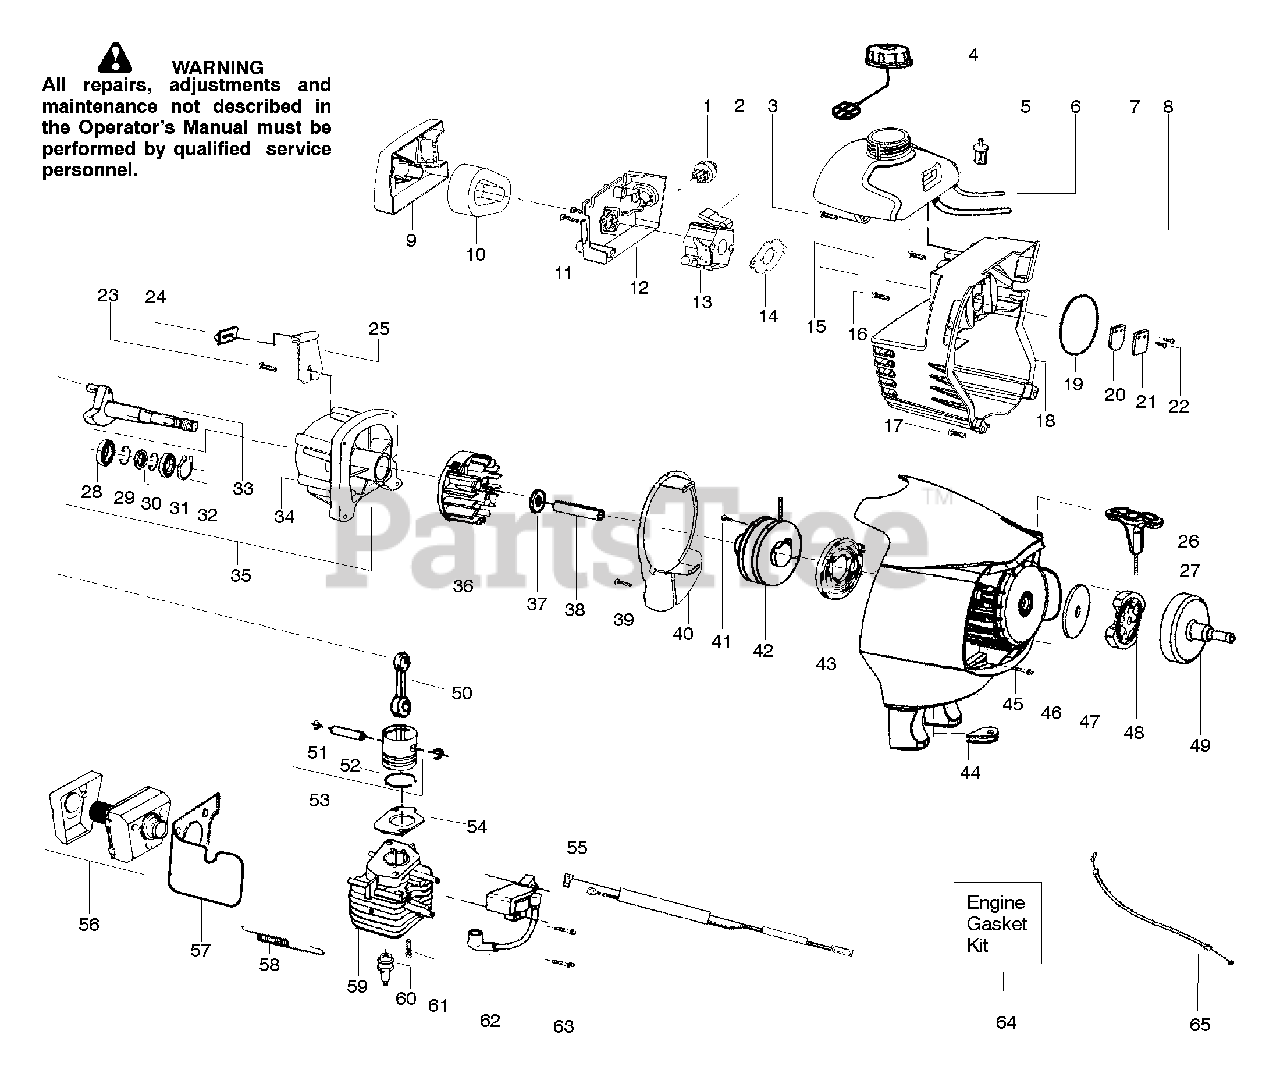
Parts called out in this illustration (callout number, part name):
1	Bulb-Purge
2	Kit-Choke Lever
3	Screw-tank
4	Cap-Fuel w/ret.
5	Assy-Fuel pickup
6	Kit-Fuel line
7	Kit-Fuel/Purge line
9	Cover-Air box
10	Filter-Air
11	Screw-Carb.
13	Assy-Carb (WT628)
14	Gasket-Carb. (kit)
15	Assy-Fuel Tank
16	Screw-Crankcase
17	Screw-Shroud
19	O-ring-Shroud (kit)
20	Valve-Reed
21	Stop-Reed
22	Screw-Reed stop
23	Screw-Retainer
24	Isolator-Tank
25	Ret.-Tank
26	Handle-Starter
27	Kit-Rope
28	Bearing-Inner
29	Retainer
31	Bearing-Outer
32	Ret.-Crankshaft
33	Assy-Crankshaft
34	Assy-Crankcase
35	Assy-C'case/C'shaft
36	Assy-Flywheel
39	Screw-Baffle
40	Plate-Baffle
41	Screw-Rope
42	Kit-Pulley
43	Spring-Starter
45	Screw-F/hsg.
46	Assy.-Fan Housing
47	Washer-Clutch
48	Assy-Clutch
49	Drum-Clutch
50	Assy-Conn. Rod
51	Ret.-Piston pin
52	Ring-Piston
53	Kit-Piston
54	Gasket-Cylinder (kit)
55	Assy-Leadwire
56	Kit-Muffler
58	Spring-Muffler
59	Cylinder
60	Plug-Spark (RCJ-6Y)
61	Bolt-Cyl. 1/4-20"
62	Module-Ignition
63	Screw-Module
64	Kit-Gasket
65	Assy-Throttle cable
